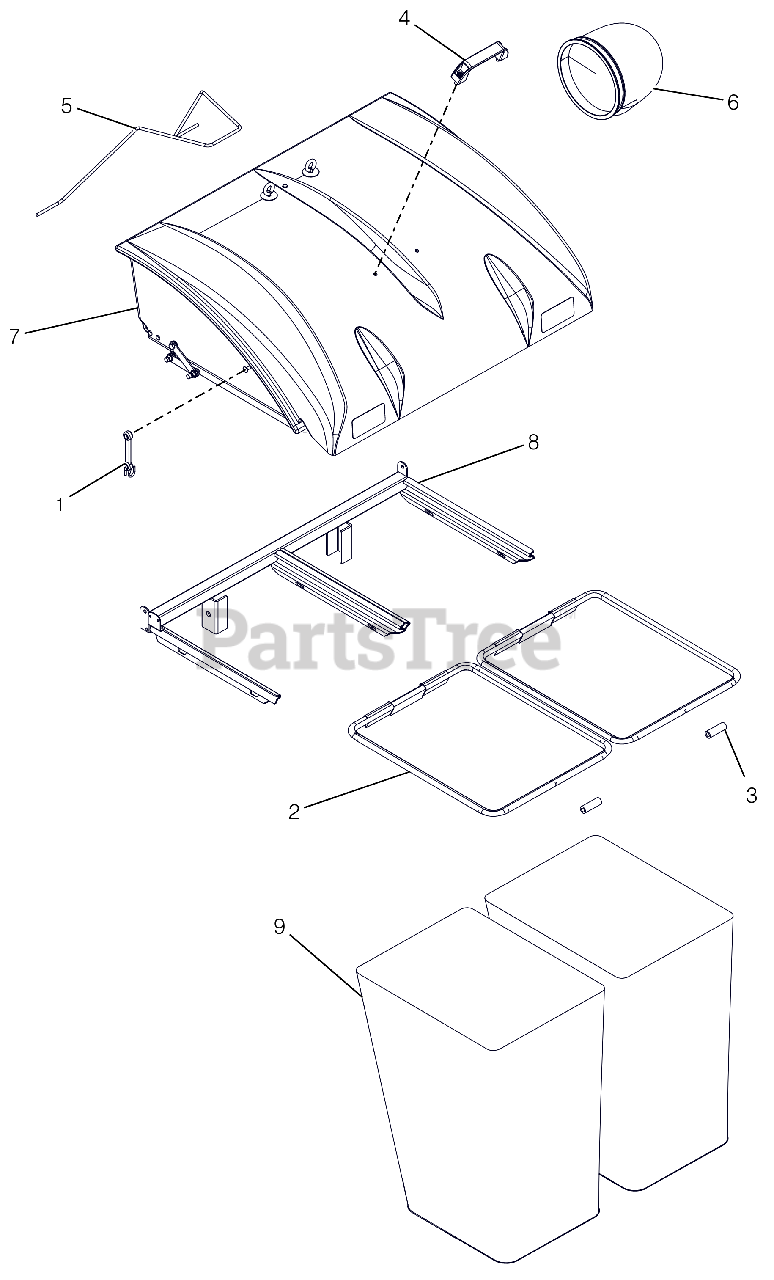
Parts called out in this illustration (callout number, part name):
1	RUBBER HOOD STRAP
2	BAG WIREFORM
3	RUBBER CONNECTOR
5	ROPE, BAGGER RELEASE
6	ELBOW, PECO 3 BAG BAGGER
7	HOOD ASM PECO 2 BAG
8	FRAME ASM PECO 2 BAG
9	PECO BAGGER BAG
